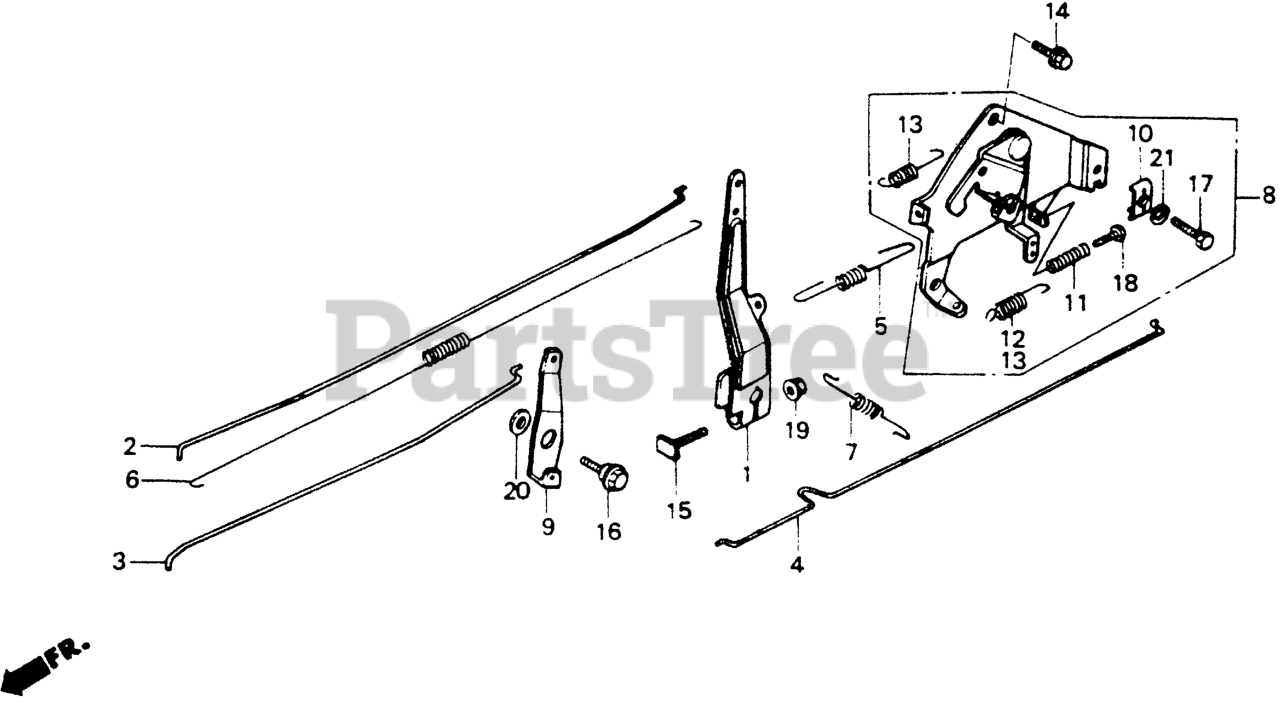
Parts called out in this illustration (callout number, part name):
1	ARM, GOVERNOR
2	ROD, GOVERNOR
3	ROD, CHOKE
4	ROD, JOINT
5	SPRING, GOVERNOR
7	SPRING, GOVERNOR PRIMARY
8	CONTROL ASSY.
9	LEVER, CHOKE JOINT (Honda Code 2090199). (NOT AVAILABLE)
10	HOLDER, CABLE
11	SPRING, CONTROL ADJUSTING Use from Engine SN 2327377.
12	SPRING, CABLE RETURN
13	SPRING, CABLE RETURN
14	BOLT, FLANGE (6X12) (CT200)
15	BOLT, GOVERNOR ARM
16	BOLT, FLANGE (6MM)
17	BOLT, RECESSED (5X16)
18	SCREW, PAN (5X20)
19	NUT, FLANGE (6MM)
20	WASHER, PLAIN (6MM)
21	WASHER, SPRING (5MM)
